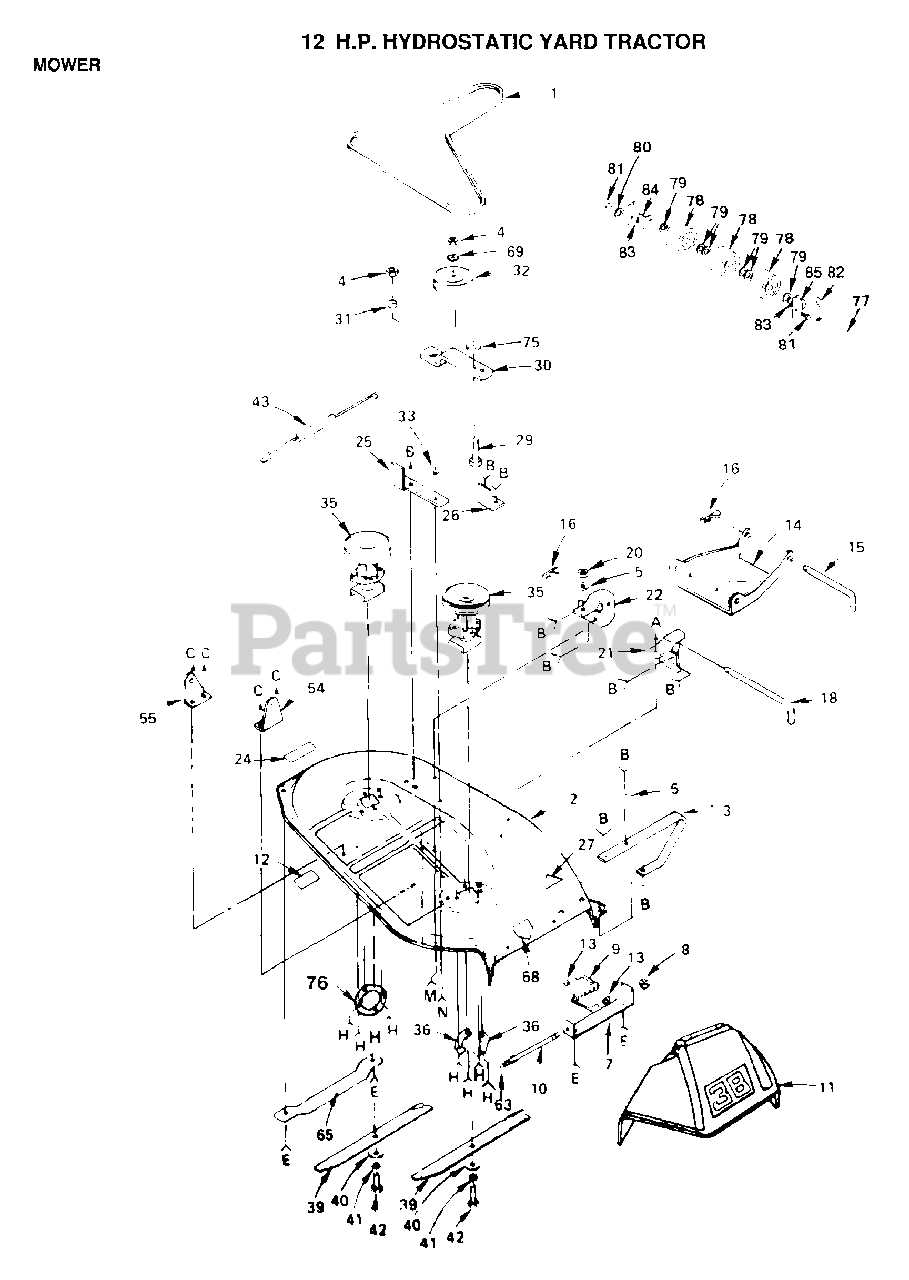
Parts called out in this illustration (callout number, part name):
1	BELT-V.79.1.MWR
5	WASHER M
8	NUT PUSH M
10	ROD-HINGE T
11	DEFLECTOR-SHLD T
13	CAP-SLEEVE LT
14	LINK.PARALLEL
15	"ROD, FRT. PARAL T"
16	SPRING.RETAINER
18	HINGE PIN T
21	BRACKET RH LT
22	BRACKET LH T
24	DECAL YT
25	SUPPORT ARM T
26	STOP T
31	SPACER RETAINER
32	PULLEY IDLER
33	"WASHER, WEAR LT"
35	"JACKSHAFT.38""LT"
36	SUPPORT PLATE LT
39	"BLADE.38"" HI-LI"
40	WASHER
42	BOLT.3/8-24X1-1/2
43	"SPRING.EXT.8.5"""
54	"BRKT,SUSP RH T"
55	"BRKT,SUSP REAR LH"
63	WASHER
65	RUNNER-LH M
68	DECAL WARNING
69	WASHER
75	WASHER
76	SUPPORT T
77	PIVOT PIN T
78	ROLLER T
79	WASHER T
81	BOLT
82	COTTER PIN
84	BRACKET LH T
85	BRACKET RH T
